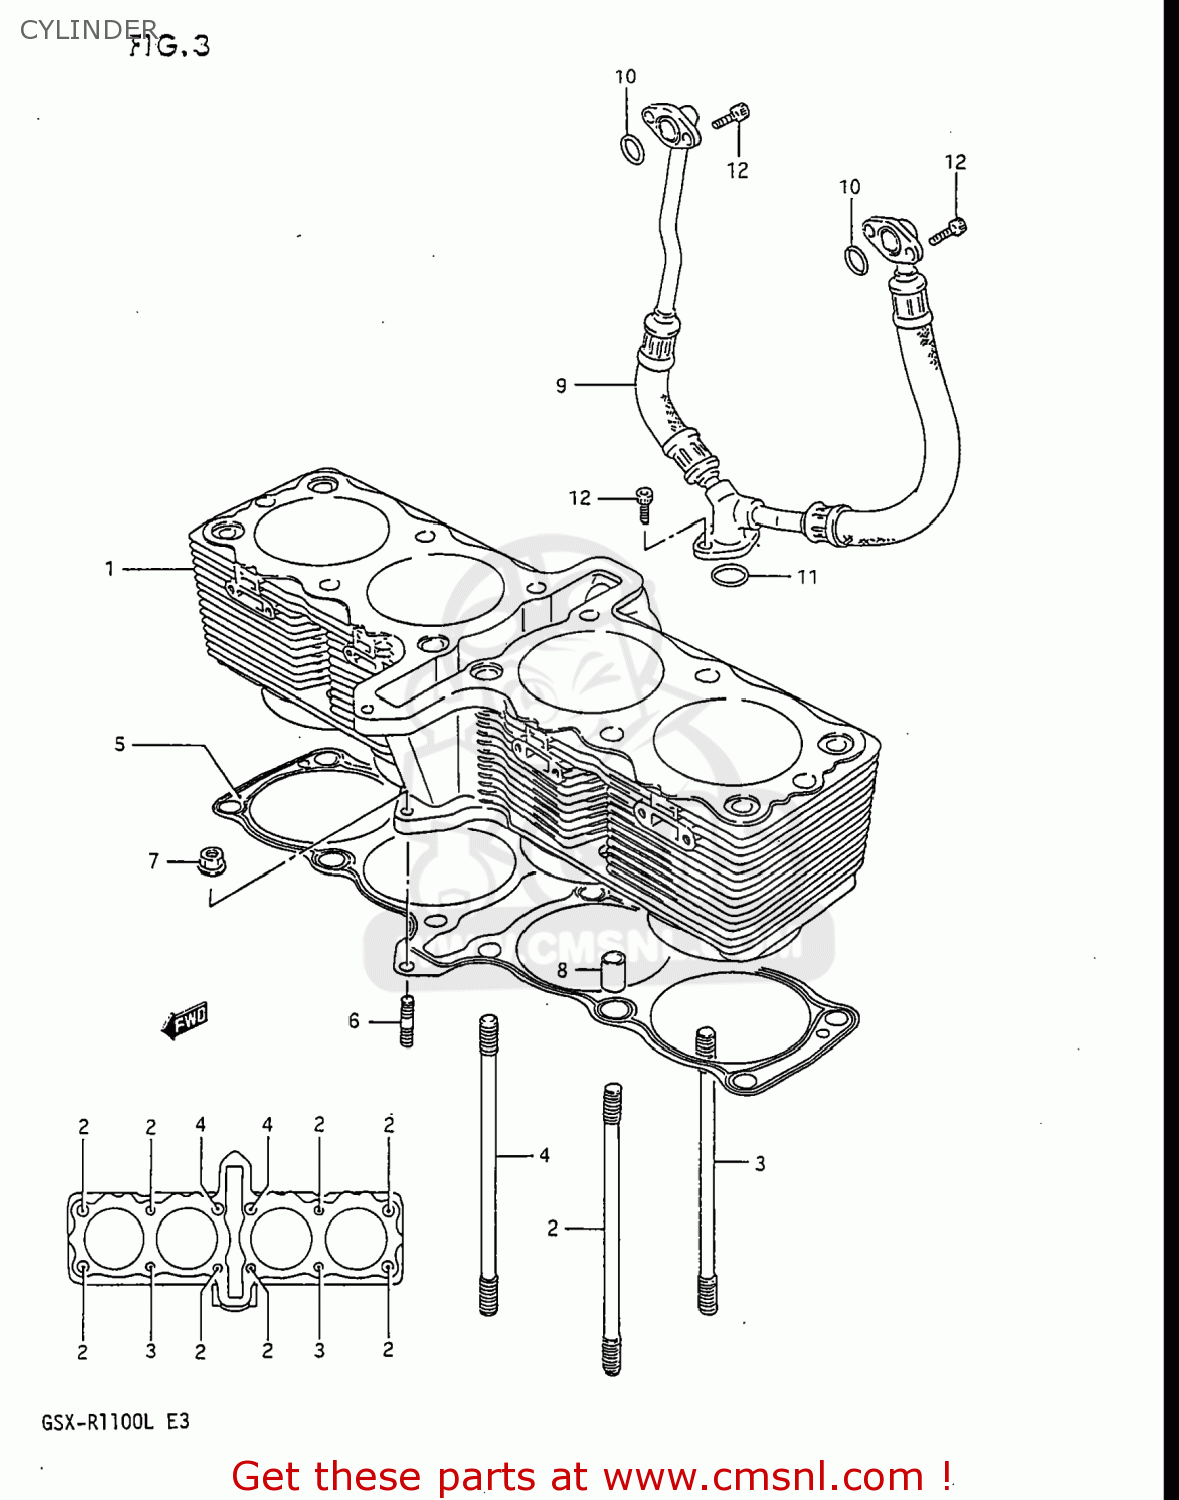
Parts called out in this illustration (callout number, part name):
1	CYLINDER
2	BOLT,STUD
3	BOLT,STUD
4	BOLT,STUD
5	GASKET,CYLINDER (NAS)
6	STUD BOLT L:20
7	NUT 6MM
8	PIN
9	HOSE
10	O RING(D:2.5,ID:13.8)
11	O RING(D:2.4,ID:15.8)
12	BOLT
